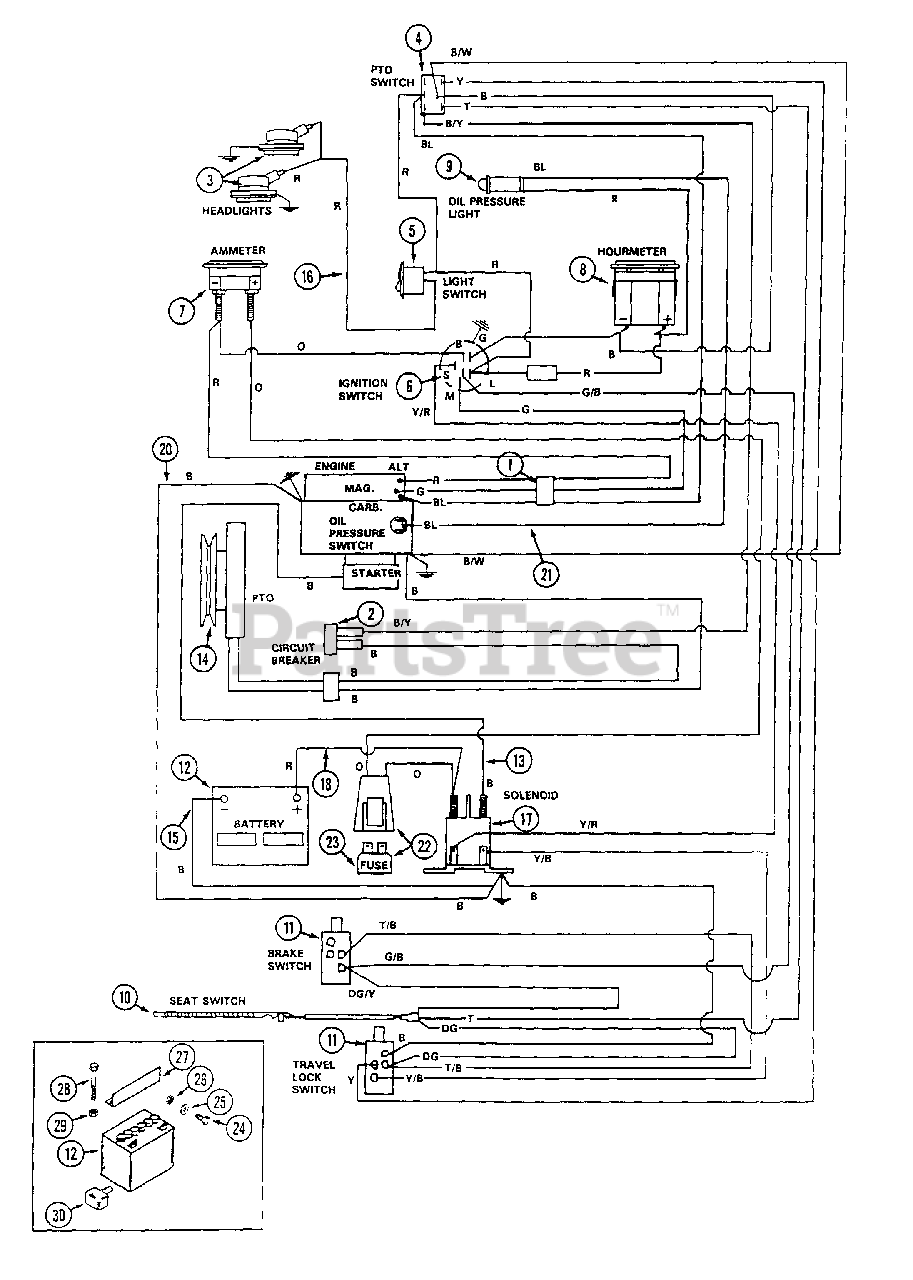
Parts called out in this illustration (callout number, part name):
1	HARNESS - wire, alternator and magneto
2	BREAKER - circuit, 10 amp
4	SWITCH - PTO (also use C31619 Cap)
5	SWITCH - headlight
6	SWITCH - ignition
10	SWITCH - seat
11	SWITCH - safety
12	BATTERY - 12 volt
13	WIRE - starter
15	CABLE - ground
16	WIRE - headlight
17	SOLENOID - start
18	CABLE - battery positive te solenoid
20	WIRE - ground
21	HARNESS - oil pressure switch
22	KIT - fuse holder
23	FUSE - 30 amp
24	BOLT - 1/4" - 20 x 3/4"
25	WASHER - 1/4"
26	NUT - 1/4" - 20
27	BRACKET - hold down
28	BOLT - 1/4" - 20 x 7"
29	NUT - 1/4" - 20 lock
30	COVER - terminal, battery
30	COVER - terminal, starter
